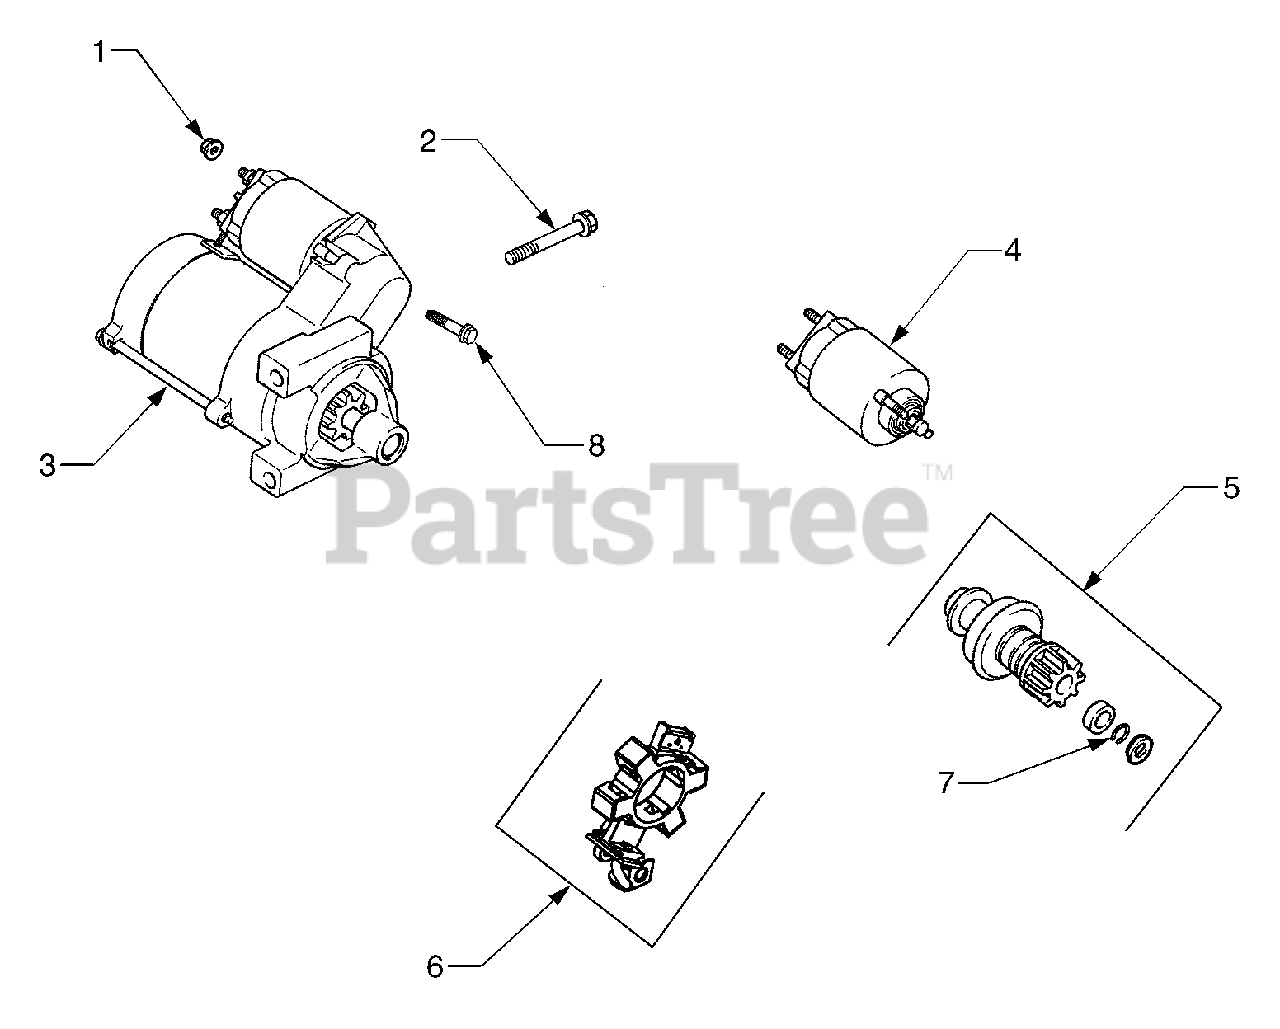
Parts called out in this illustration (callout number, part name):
1	Nut, Hex Flange M8 x 1.25"
2	Screw, Hex Flange M8 x 1.25 x 80
3	Starter, Solenoid Shift Assembly
4	Kit, Solenoid
5	Kit, Pinion Drive
7	Ring, Retainer
8	Screw, External Torx Hd.
